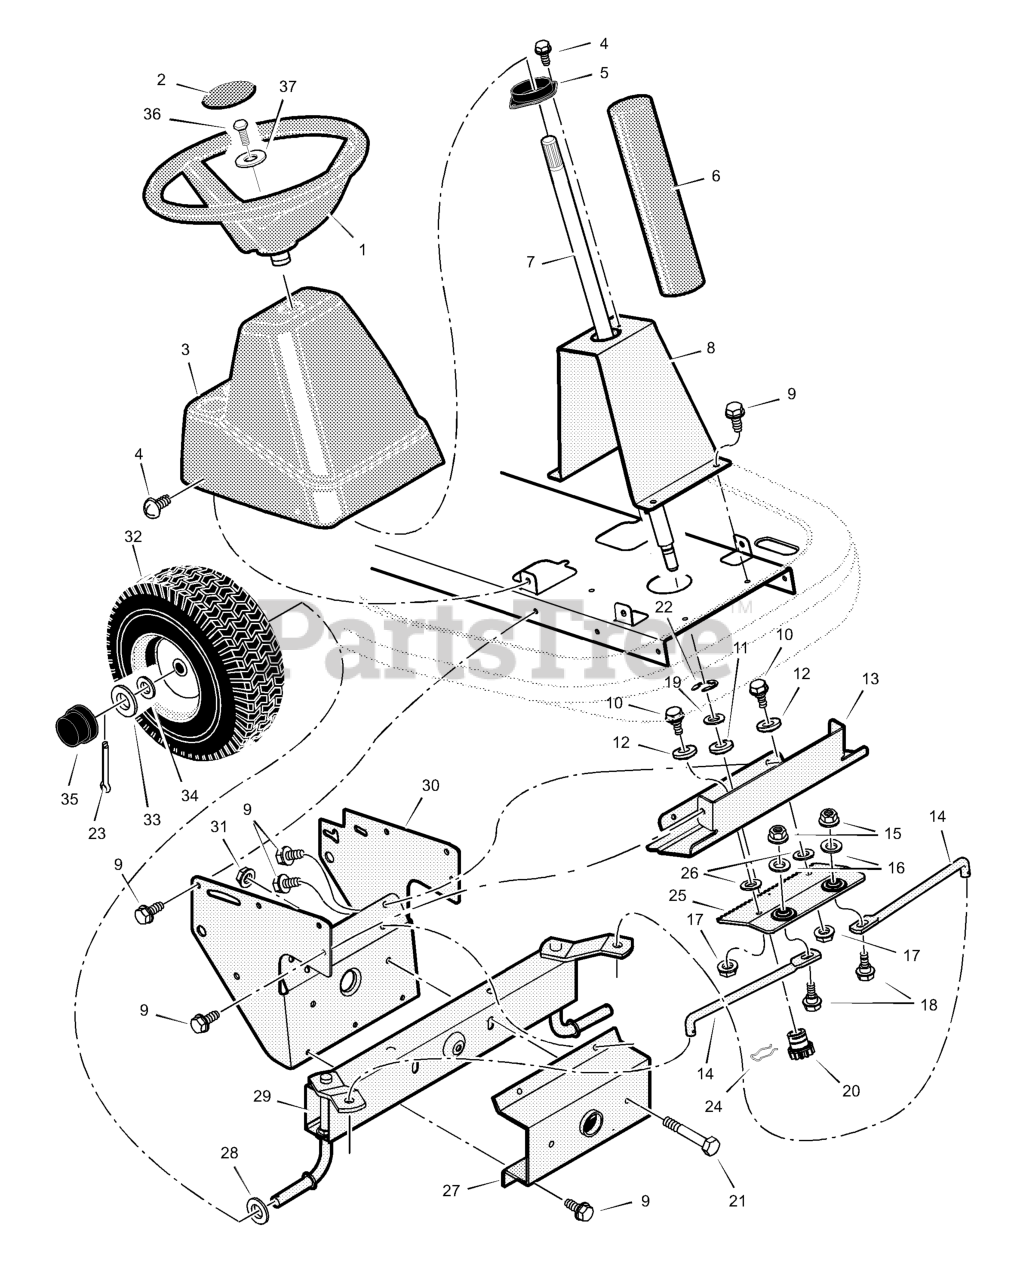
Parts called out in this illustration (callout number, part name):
1	Wheel, Steering (Gray)
2	Insert, Steering
3	Console, Low (Gray)
4	Screw
5	Bearing, Upper Steering
6	Tube, Steering (Gray)
7	Shaft, Steering
8	Support, Steering
10	Bolt, Shoulder
11	Bearing, Lower Steering
13	Plate, Gear Mounting
14	Link, Drag
15	Nut, Flange
16	Washer
17	Nut, Flange
18	Bolt, Hex
19	WASHER, 1-1.3 16G FLT
20	Gear, Pinion
21	Bolt, Hex
22	E-Ring, Retainer
23	Pin, Cotter
24	Retainer, Spring
25	Rack, Steering
26	Washer
27	Bracket, Axle Front
28	Washer
29	Axle & Spindle
30	Bracket, Support
31	Nut, Flange
32	Wheel, Front
34	Washer
35	Cap, Hub
36	Screw, Hex
37	Washer
